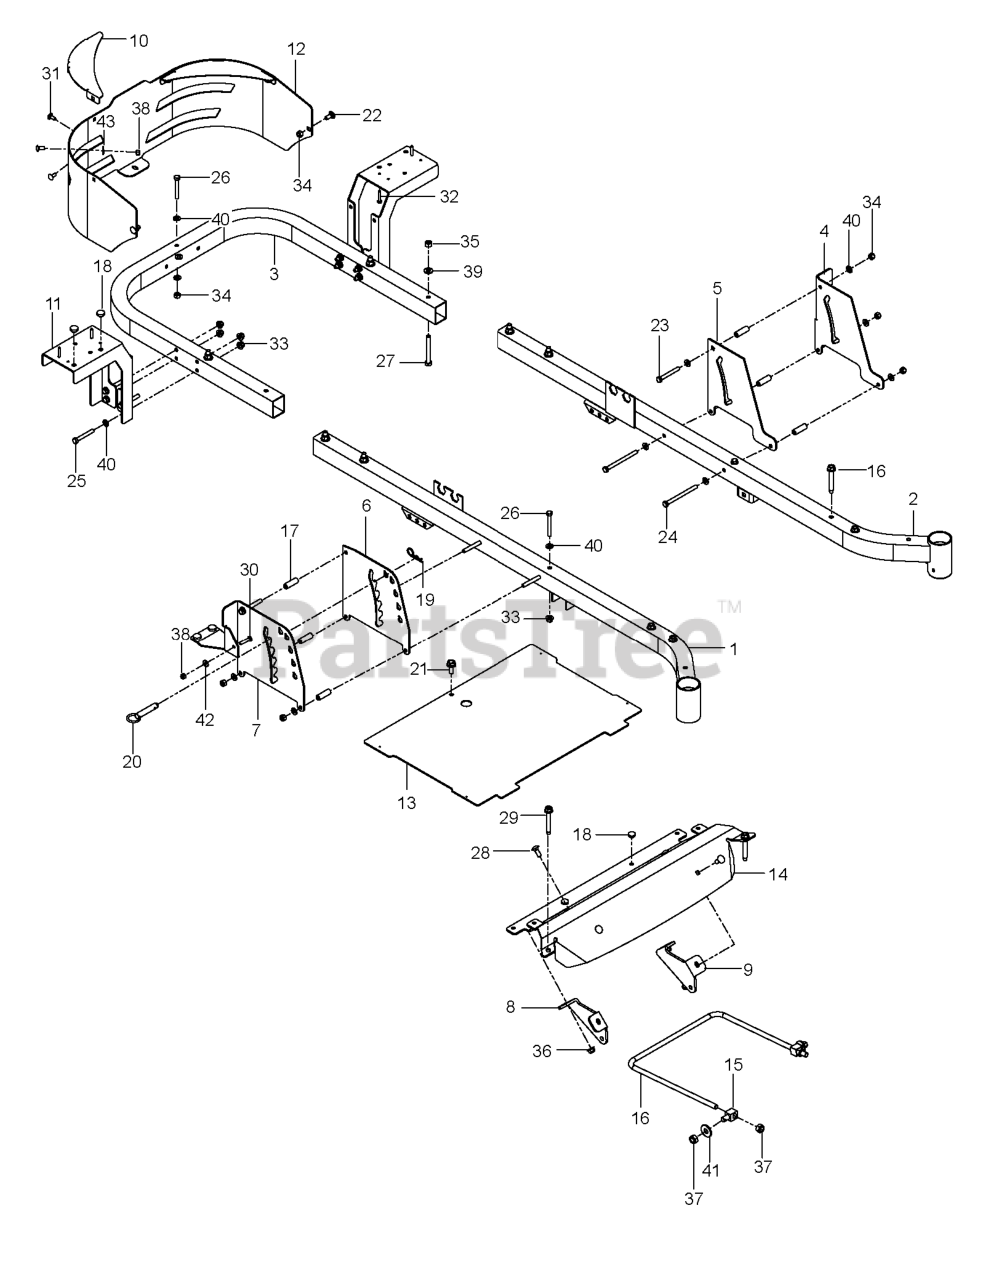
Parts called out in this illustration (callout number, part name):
1	FRAME, RT, ORANGE
2	FRAME, LT, ORANGE
3	FRAME TUBE, REAR, ORANGE
4	PLATE, OUTER BRAKE, BLACK
5	PLATE, BRAKE LATCH, BLACK
6	PLATE, DECK HEIGHT, BLACK
7	PLATE, DECK HEIGHT, BLK EZ
8	MOUNT, STRUT, RT, BLK
9	MOUNT, STRUT, LT, BLK
10	SUPPORT, CORNER, ORANGE
11	SUPPORT, FENDER, BLACK
12	GUARD, REAR, ORANGE
13	PLATE, FOOT W/DECALS EZ
14	FOOT REST WIDE ORG
16	LINK, FRONT SUSP.
17	SPACER, .334 ID X .5 OD X 1.5
18	GROMMET, BUMPER
19	KNOB W/STUD
21	HAIRPIN #4
22	BOLT 5/16C X 3/4" CARRIAGE
23	HCS 5/16-18 X 2-1/2 GR 5 ZD
24	HCS 5/16C X 4
25	BOLT.FIN HEX 5/16-18UNC X2 1/4
27	BOLT.HEX.FIN.3/8-16 X 3.GR5
28	BOLT D
32	SCR #10-12X1-1/2HEX WASH HD ZD
33	5/16-18 NYLOC FLANGE NUT
34	NUT 5/16 NYLOC
35	NUT 3/8-16 NYLOC
36	NUT 3/8-16 HEX FLG NYLOC ZD
37	7/16-14 HEX NUT W/NYL RING ZD
38	NUT.1/4-20.HEX.NYLOC.ZD
39	WASHER 3/8 SAE FLAT
40	FLAT WASHER 5/16 SAE
41	WASH USS FLAT 1/2
42	WASHER 1/4 SAE
43	WASHER 1/4 FLAT
